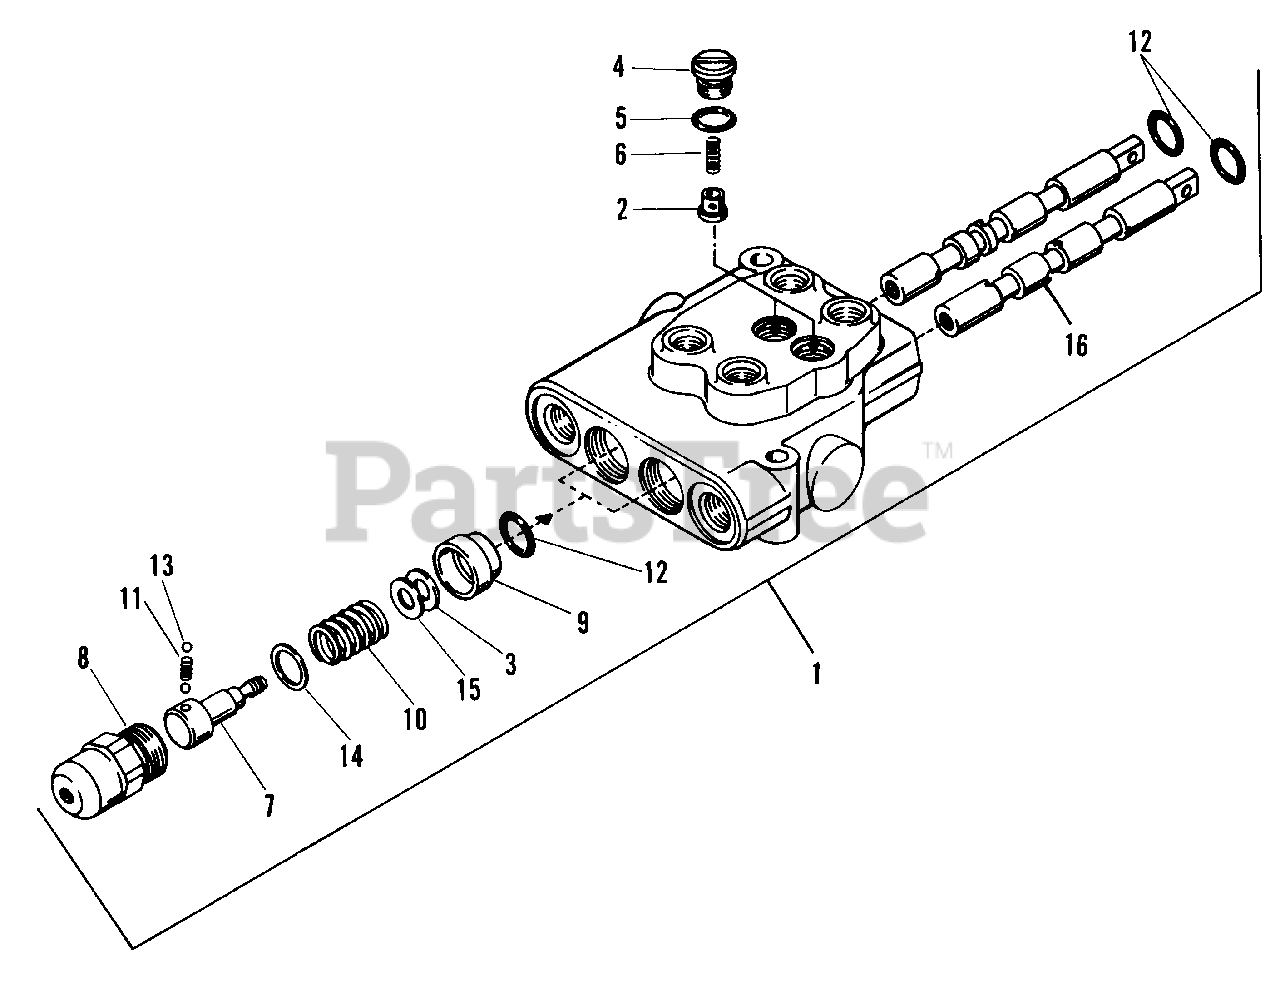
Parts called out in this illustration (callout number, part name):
1	VALVE, Hydraulic
3	WASHER,.046 Thick
7	SCREW, Detent
8	CAP ASSY.
14	WASHER, .046 Thick
15	Washer, .020 Thick (if equipped)
15	SEAL KIT, Repair
